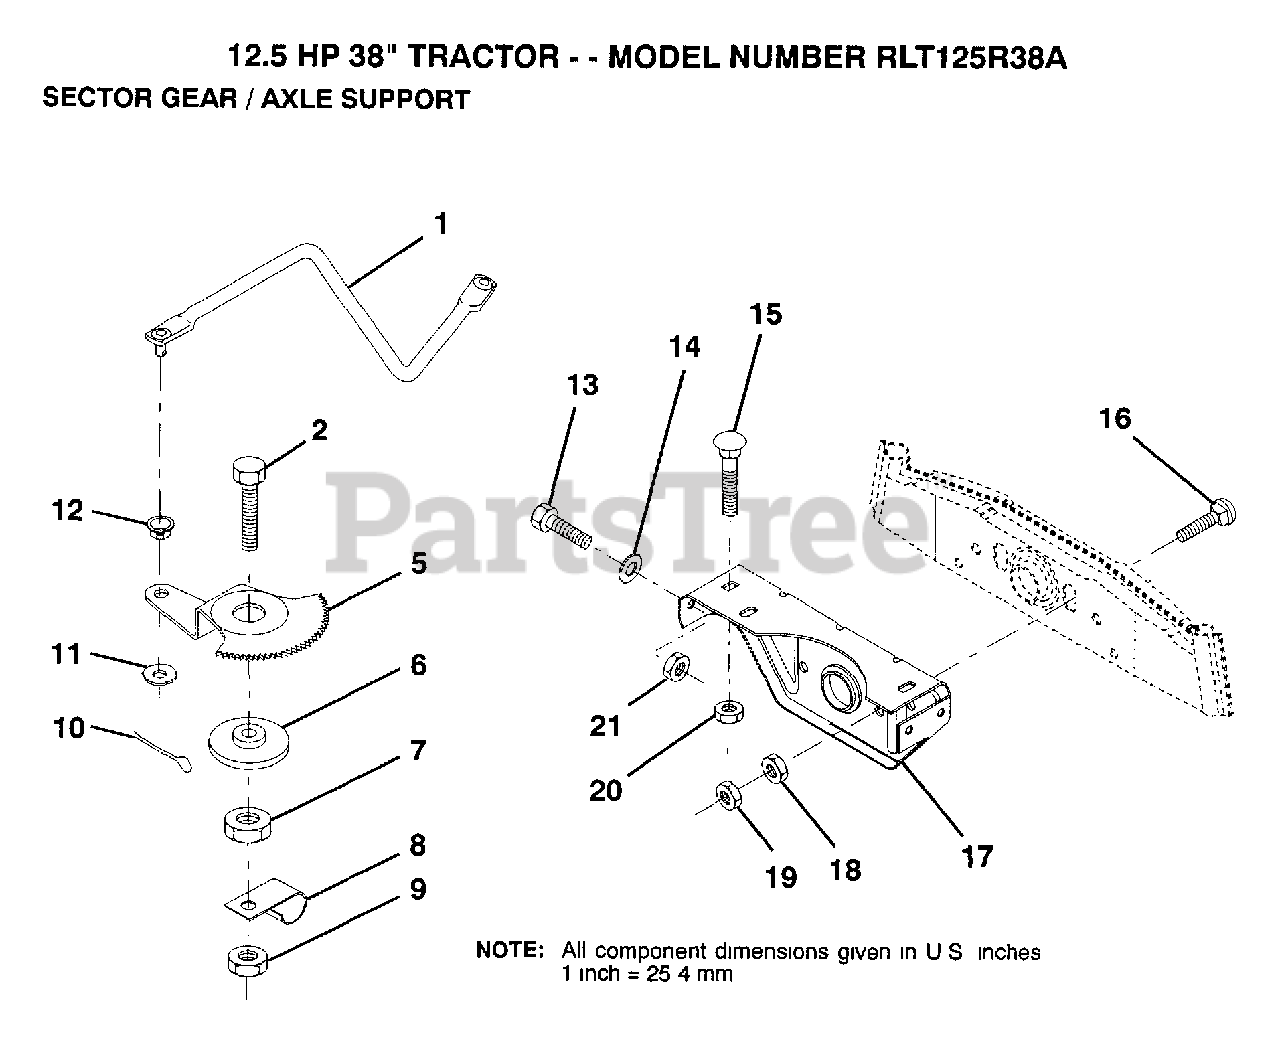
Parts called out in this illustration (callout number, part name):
1	DRAG LINK
2	"BOLT,HEX"
5	GEAR SECTOR
6	BUSHING
7	NUT
8	CLIP INSULATOR
9	NUT LTV
10	COTTER PIN
11	WASHER
12	BUSHING.DRAGLINK
13	BOLT
14	WASHER
15	BOLT
16	BOLT
17	"SUPT,FRT AXLE"
18	NUT.HEX.3/8-16UNC
19	LOCKNUT
